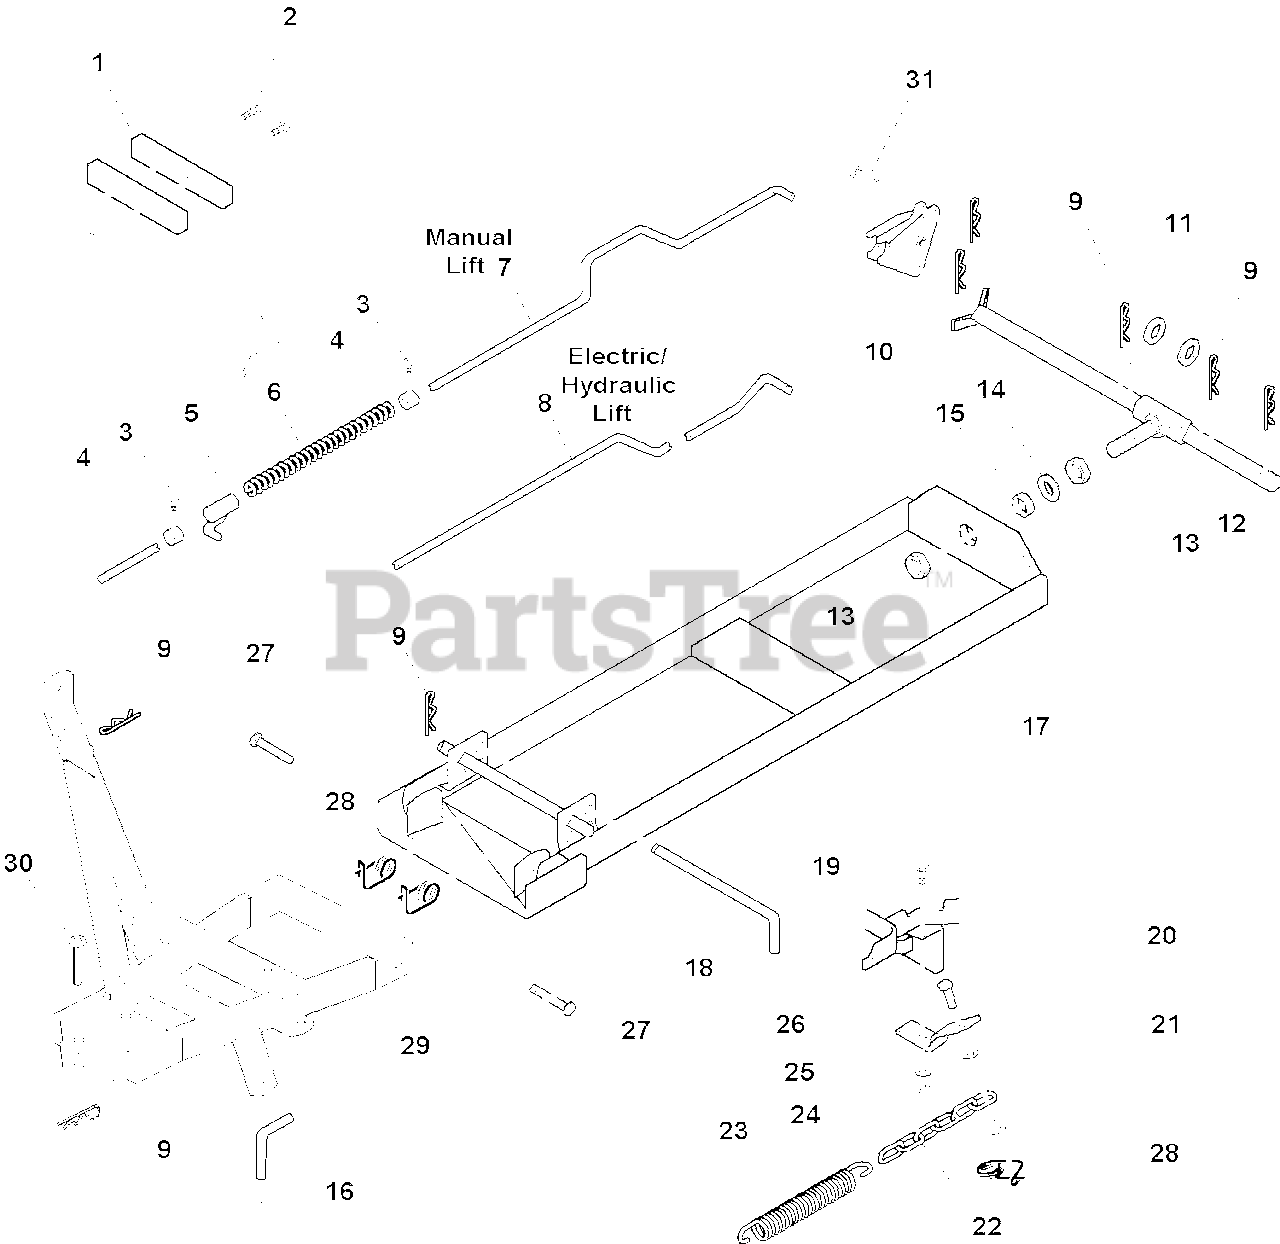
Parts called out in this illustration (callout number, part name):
1	BAR
2	CAPSCREW, Taptite, 5/16-18 x 1
3	SCREW, Set, 5/16-18 x 1/2
4	COLLAR
5	GUIDE ASSEMBLY
7	ROD, Manual Lift
8	ROD, Eletric / Hydraulic Lift
10	EXTENSION ASSEMBLY KIT
11	WASHER, 3/4
12	TUBE & BOLT ASSEMBLY
13	NUT, Hex, 5/8-11
14	WASHER, 5/8
17	REAR PUSH BAR ASSEMBLY
19	CAPSCREW, Hex Head 5/16-18 x 1
20	PIN
21	WASHER, 5/16
24	NUT, Hex, 5/16-18
25	LOCKWASHER, 5/16
26	BRACKET
27	PIN
28	RETAINER, Pin
29	PUSH BAR ASSEMBLY
